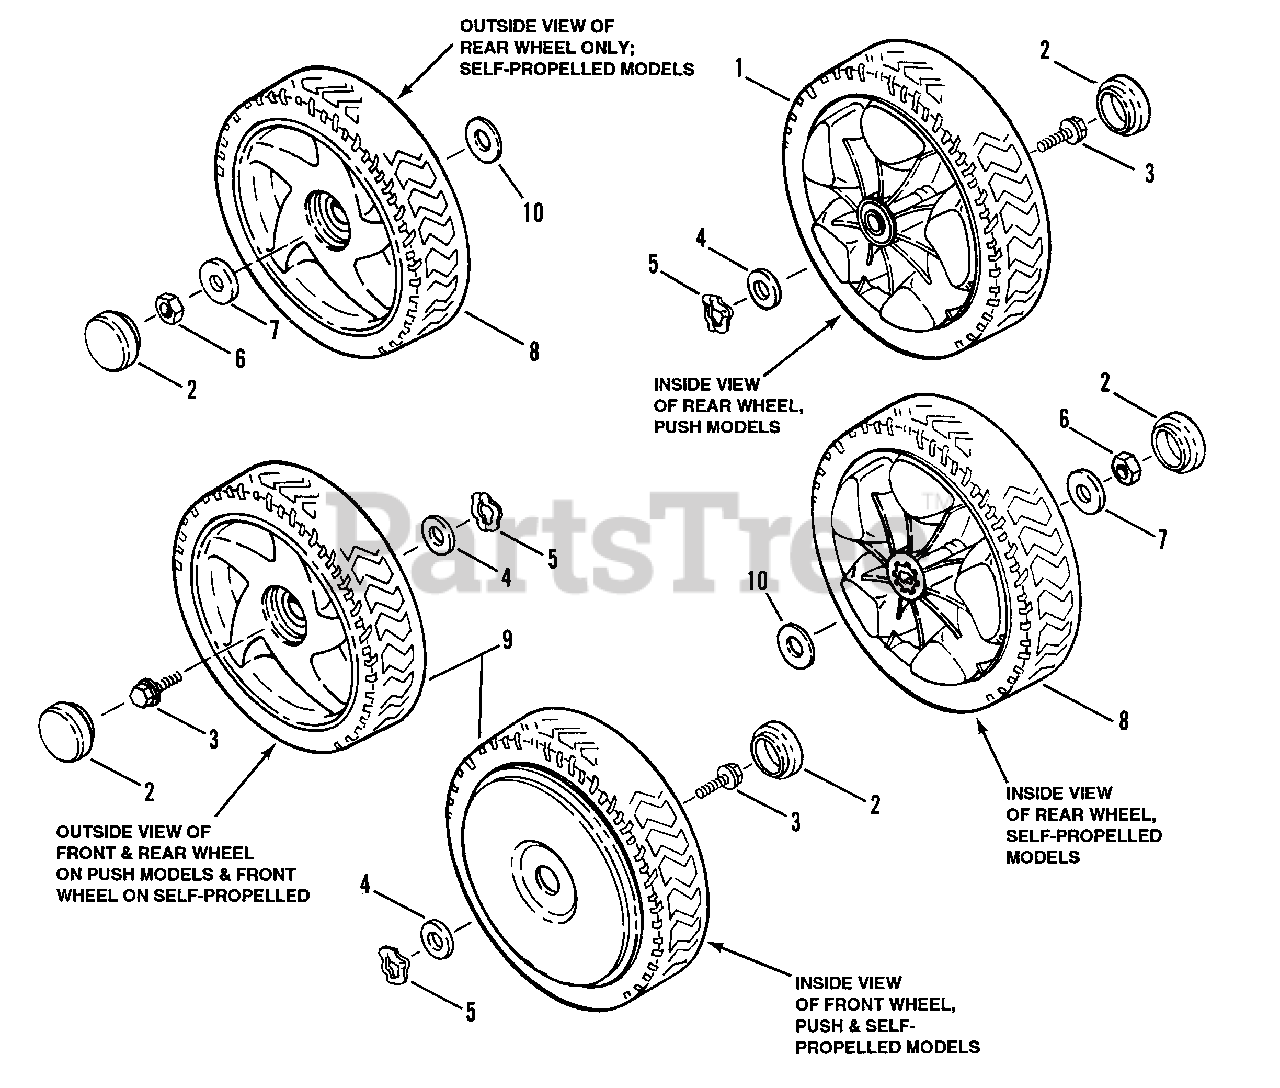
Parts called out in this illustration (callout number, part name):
1	ASSEMBLY Wheel, 8.0 x 2.0 Plastic (Rear)
2	CAP, Hub
3	SCREW, 5/16-18 x 5/8" Hex Self-Tapping
4	WASHER, 17/32 I.D. Flat
5	WASHER, 17/32 Wave
6	NUT, 7/16-20 Hex Center Lock
7	WASHER, 7/16 Flat
8	ASSEMBLY, Wheel, 8.0 x 2.0 Plastic (Rear)
9	ASSEMBLY, Wheel, 8.0 x 2.0 Plastic (Front)
10	WASHER, 9/16 x 1-1/16" O.D. Thrust
